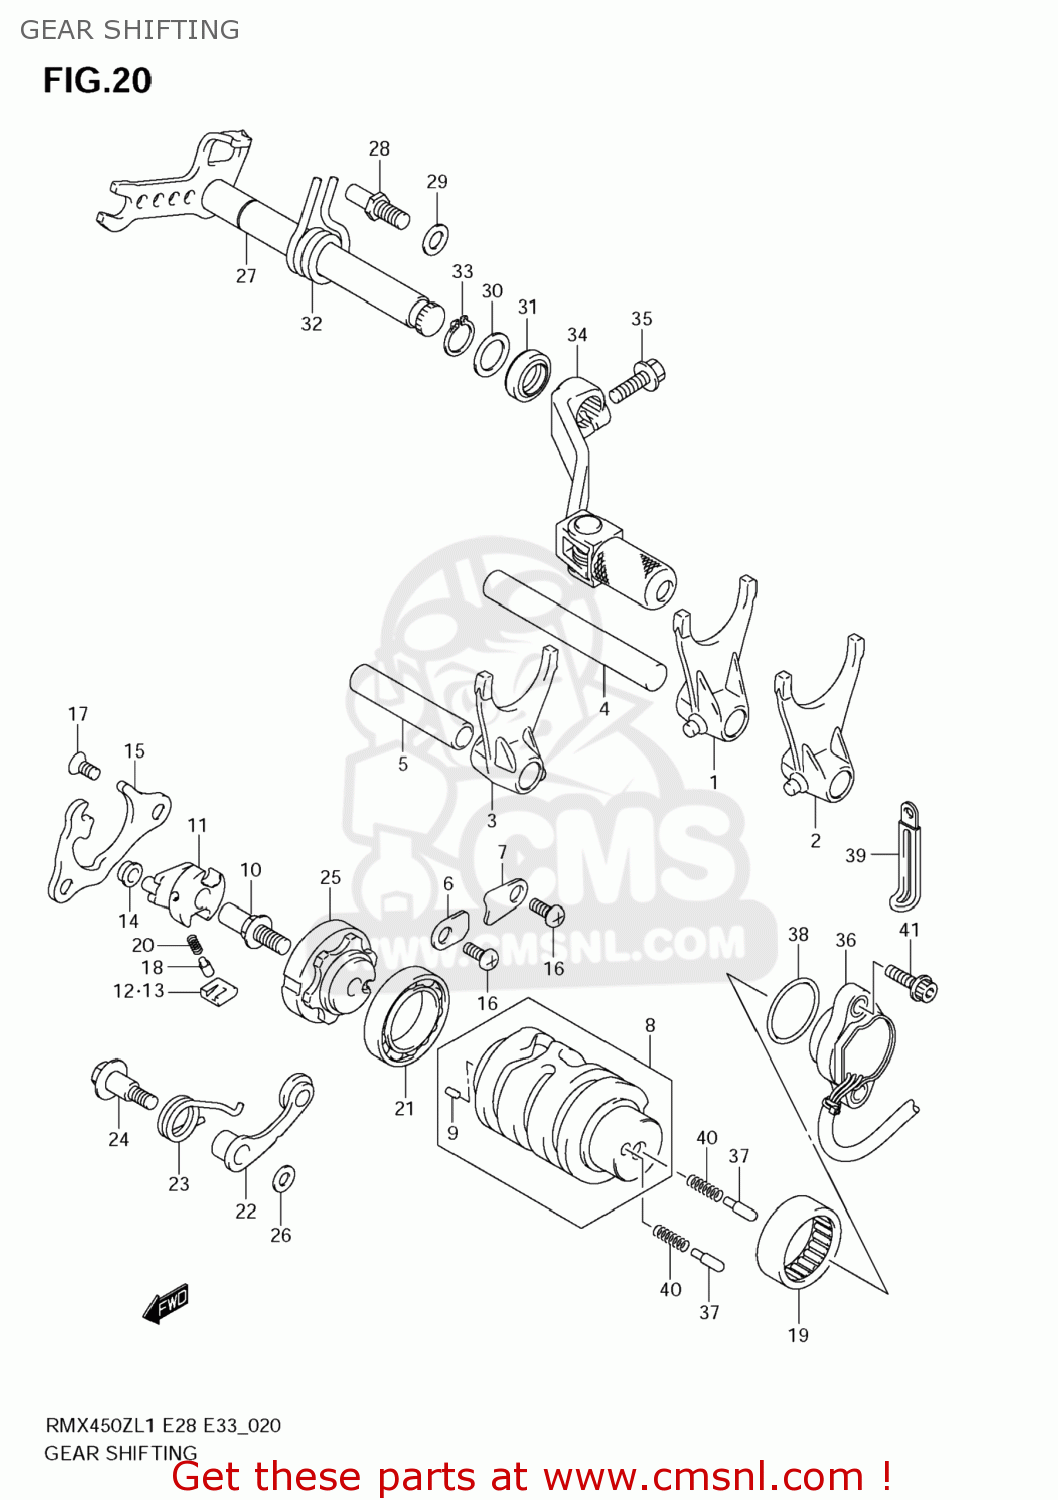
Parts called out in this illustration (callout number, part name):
1	FORK,GEAR SHIFT NO.1
2	FORK,GEAR SHIFT NO.2
3	FORK,GEAR SHIFT NO.3
4	SHAFT,GEAR SHIFT FORK NO.1
5	SHAFT,GEAR SHIFT FORK NO.2
6	RETAINER
7	RETAINER,BEARING
8	CAM,GEAR SHIFT
9	PIN
10	PIN,GEAR SHIFT CAM
11	SHIFTER,GEAR SHIFT CAM
12	PAWL,GEAR SHIFT NO.1
13	PAWL,GEAR SHIFT NO.2
14	ROLLER,GEAR SHIFT CAM SHIFTER
15	LIFTER,GEAR SHIFT PAWL
16	SCREW(6X12)
17	SCREW(6X12)
18	PIN
19	BEARING(25X32X12)
20	SPRING
21	BEARING
22	STOPPER,GEAR SHIFT CAM
23	SPRING,GEAR SHIFT CAM STOPPER
24	BOLT,SHIFT CAM STOPPER
25	PLATE,GEAR SHIFT CAM STOPPER
26	WASHER
27	SHAFT,GEAR SHIFT
28	STOPPER,GEAR SHIFT ARM
29	SHIM(8.8X14X1)
30	SHIM(14X20X1)
31	SEAL,OIL(14X22X7.3)
32	SPRING
33	CIRCLIP
34	LEVER ASSY,GEAR SHIFT
35	BOLT
36	BASE ASSY,GEAR SHIFT TERMINAL
37	PIN(5X15.5)
38	O RING(D:2.4,ID:26.2)
39	CLAMP(L:45)
40	SPRING
41	BOLT
